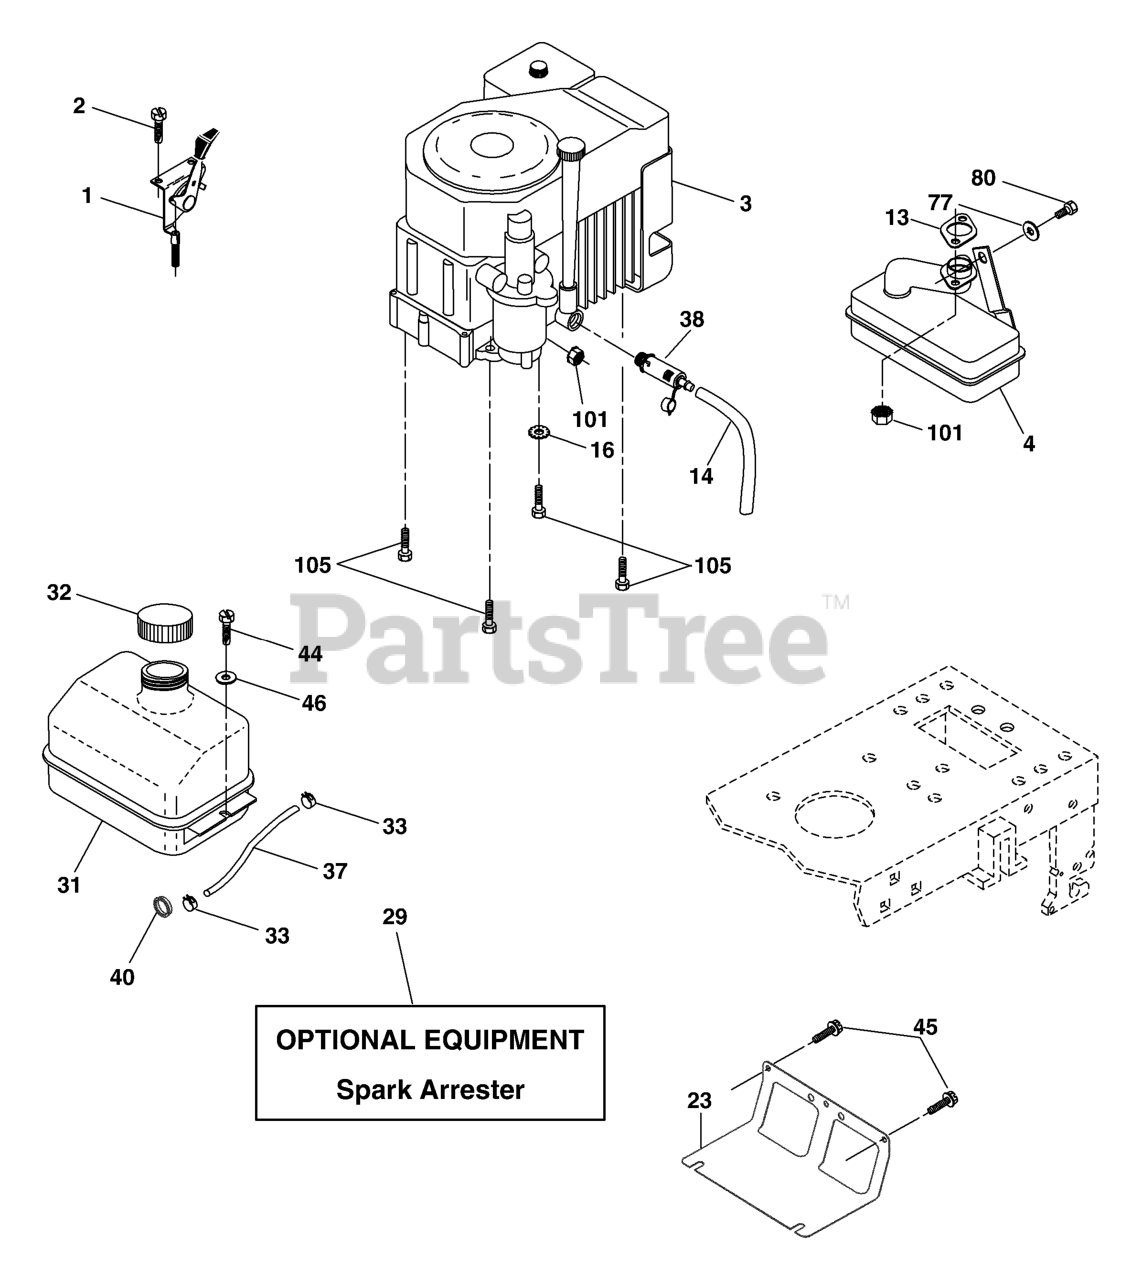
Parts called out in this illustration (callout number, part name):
1	CONTROL.THROTTLE.LT/YT
2	SCREW
4	MUFFLER.KOHL.CV491.W/PORT
13	KOHLER GASKET
14	TUBE, DRAIN OIL ASM.
16	LOCKWASHER
23	SHIELD.BROWNING.DBR.GUARD
29	KIT.SPARK ARRESTOR 794945 B&S
31	TANK.ASM.FUEL.FRONT.W/CAP
32	FUEL CAP
33	HOSE CLAMP
37	LINE.FUEL.20
38	PLUG DRAIN OIL EASY
40	BUSHING.SNAP.NYL.BLK.
44	SCREW HEXWSHR 1/4-20X3/4
45	SCREW, 3/8-16X3/4
46	WASHER
77	WASHER
80	Bolt Hex Hd 5/16-18unc x 1/2
101	FLANGE NUT
105	SCREW 3/8-16X1
